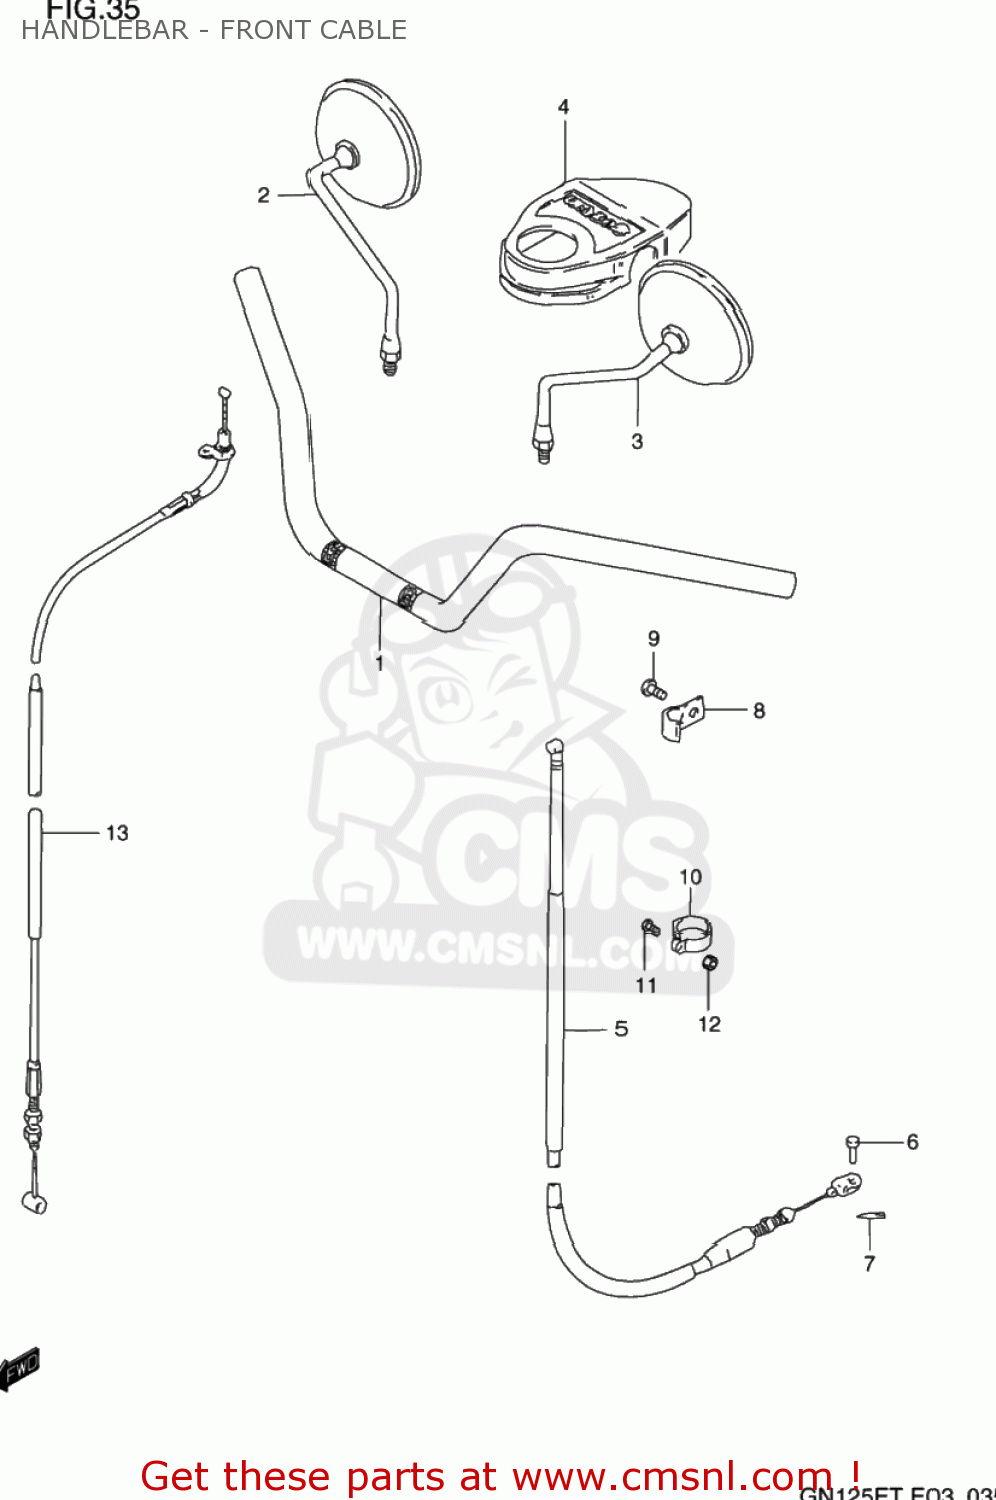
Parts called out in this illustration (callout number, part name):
1	HANDLEBAR
2	MIRROR ASSEMBLY,RIGHT
3	MIRROR ASSEMBLY,LEFT
4	COVER,STEERING HEAD
5	CABLE ASSEMBLY,CLUTCH
6	PIN(L:13)
7	PIN
8	CLAMP,CLUTCH CABLE NO.1
9	SCREW
10	CLAMP,CABLE
11	SCREW
12	NUT
13	CABLE ASSY,THROTTLE
